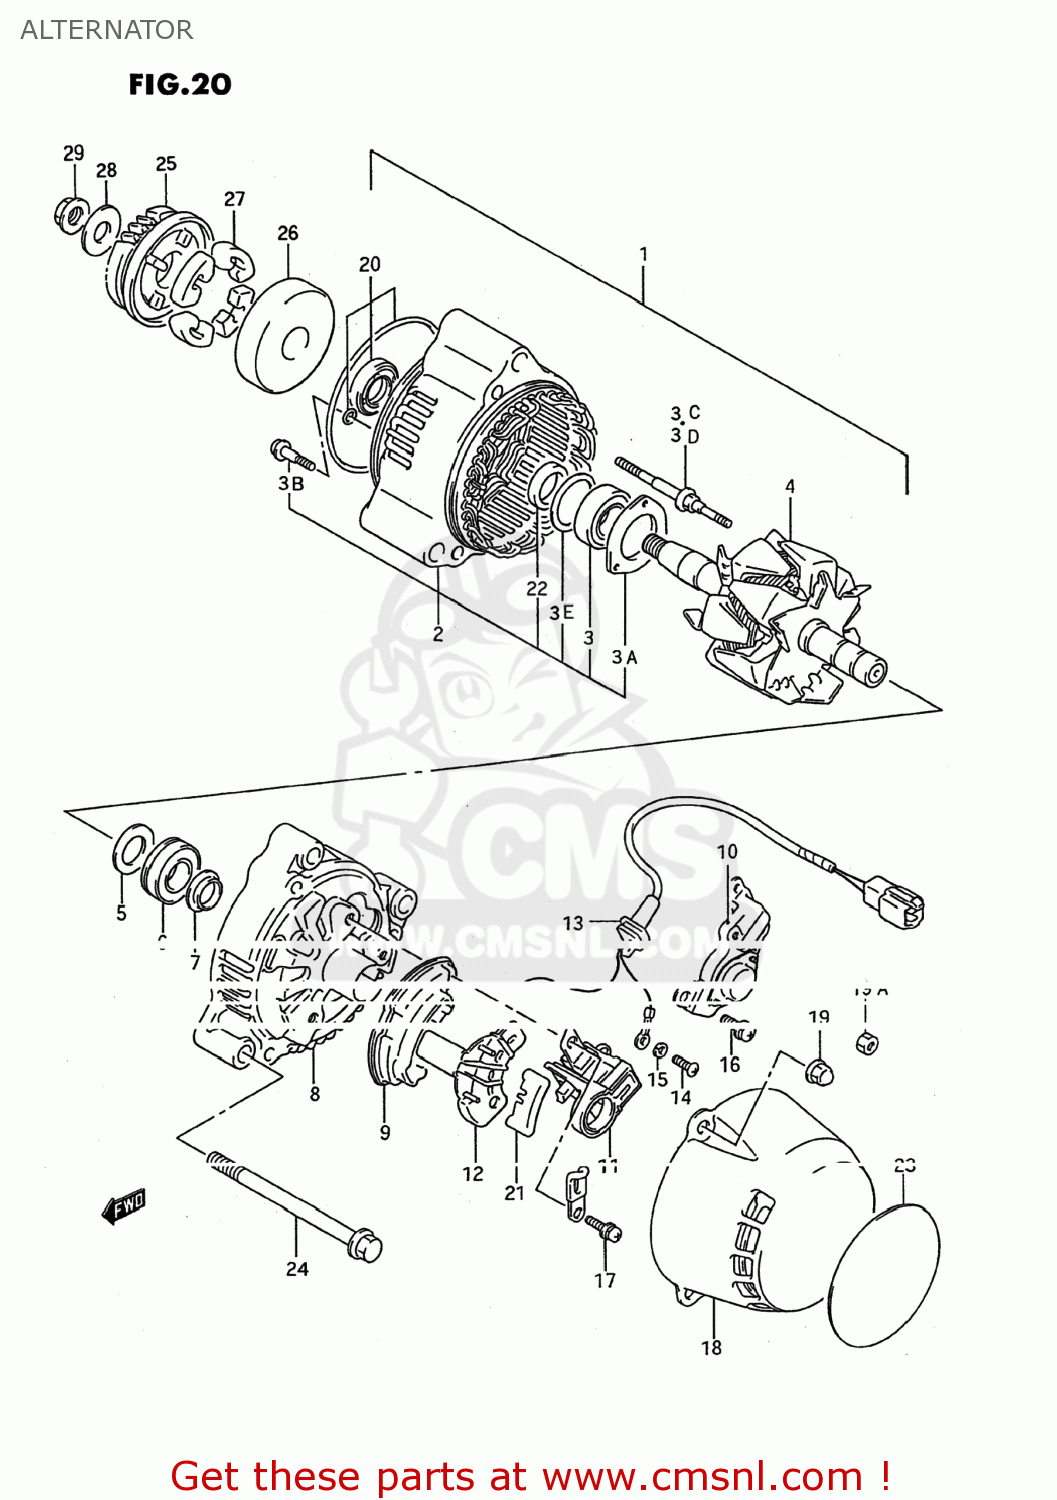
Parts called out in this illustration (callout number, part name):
1	ALTERNATOR ASSEMBLY
2	FRAME,DRIVE END
3	BEARING
3A	RETAINER
3B	SCREW,BEARING RETAINER
3C	STUD BOLT
3D	STUD BOLT
3E	COVER,BEARING
4	ROTOR ASSEMBLY
5	COVER,BEARING
6	BEARING
7	COVER(2)
8	FRAME,END
9	HOLDER,RECTIFIER
10	REGULATOR
11	HOLDER,BRUSH
12	COVER,RECTIFIER
13	WIRE,LEAD
14	SCREW
15	LOCK WASHER
16	SCREW
17	SCREW
18	COVER
19	NUT
19A	NUT ,5MM
20	SEAL SET,OIL
21	BUSH
22	SPACER
23	PROTECTOR,ALTERNATOR
24	BOLT
25	GEAR,GENERATOR DRIVEN
26	HOUSING,GENERATOR GEAR
27	DAMPER,GENERATOR DRIVEN
28	WASHER
29	NUT
